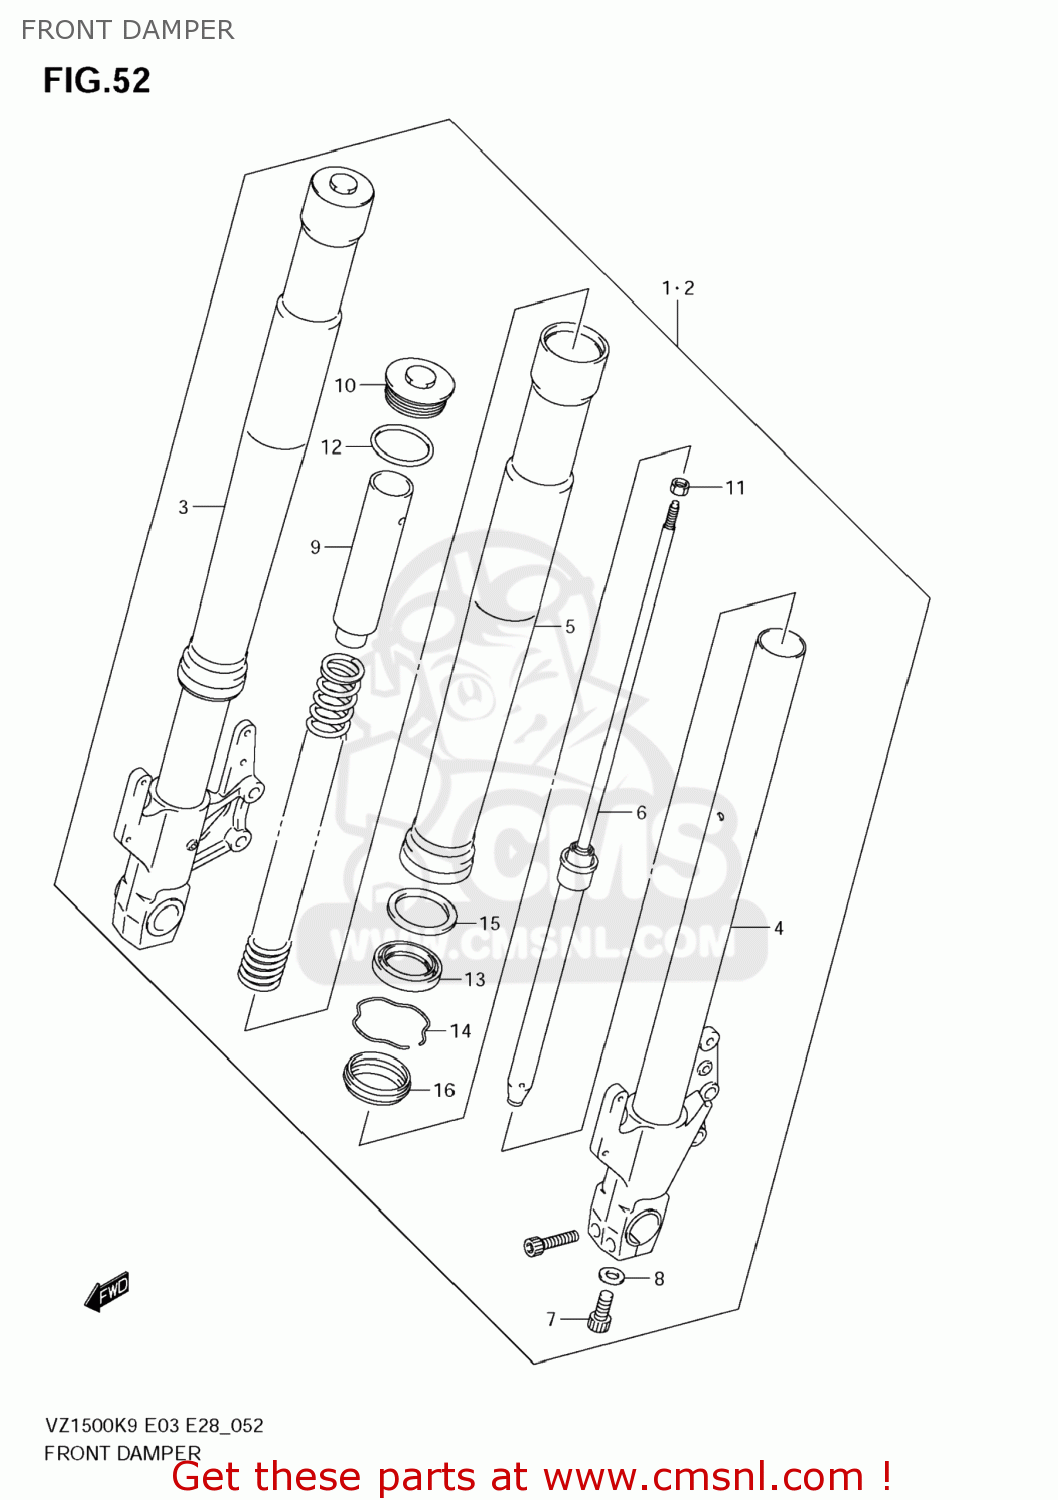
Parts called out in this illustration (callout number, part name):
1	DAMPER ASSY,FR FORK,R
2	DAMPER ASSY,FR FORK,L
3	TUBE,INNER,R
4	TUBE,INNER,L
5	TUBE,OUTER
6	CYLINDER
7	BOLT
8	GASKET (NAS)
9	SPACER,SPRING
10	CAP
11	NUT,ROD
12	O RING
13	SEAL,OIL
14	RING,STOPPER
15	WASHER
16	SEAL,DUST
